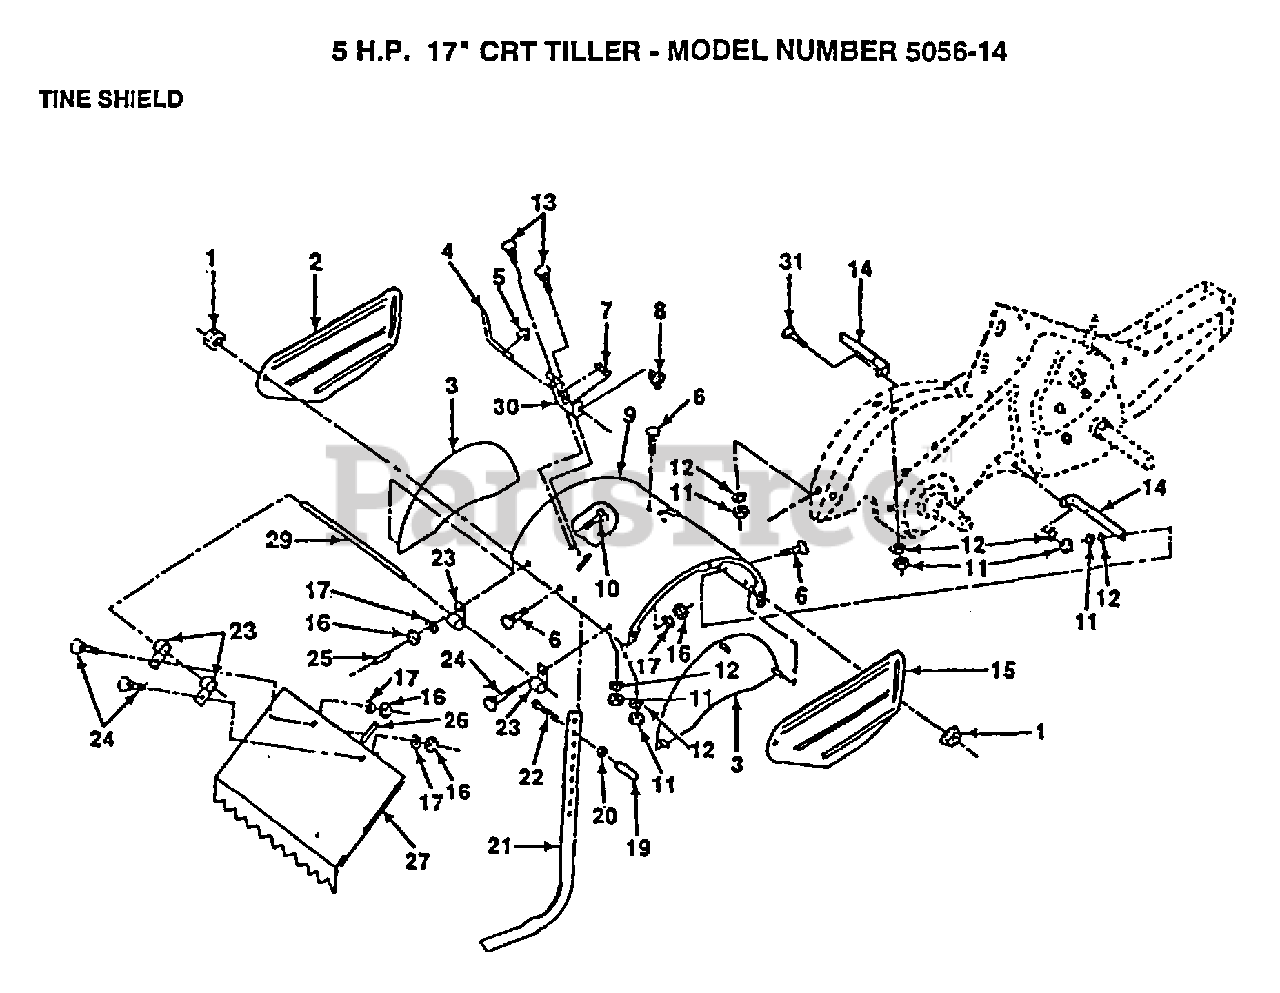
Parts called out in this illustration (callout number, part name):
1	NUT
2	SHIELD.SD.OUT.LH
3	SHLD SIDE
4	STAKE PIN TI
5	KLIP RING TI
6	BOLT
7	SPRING TI
8	SPRING CRT
10	BOLT
11	NUT.HEX.5/16-18
12	LOCKWASHER
13	BOLT CRT
14	BRKT SHIELD TINE
15	SHIELD.SD.OUT.RH
17	LOCKWASHER
19	GRIP CRT
20	NUT.HEX.3/8-16UNC
22	BOLT
23	HINGE CRT
24	BOLT
25	VINYL CAP TI
26	PAD IDLER TI
29	PIN HINGE
30	LATCH BRACKET TI
31	BOLT
